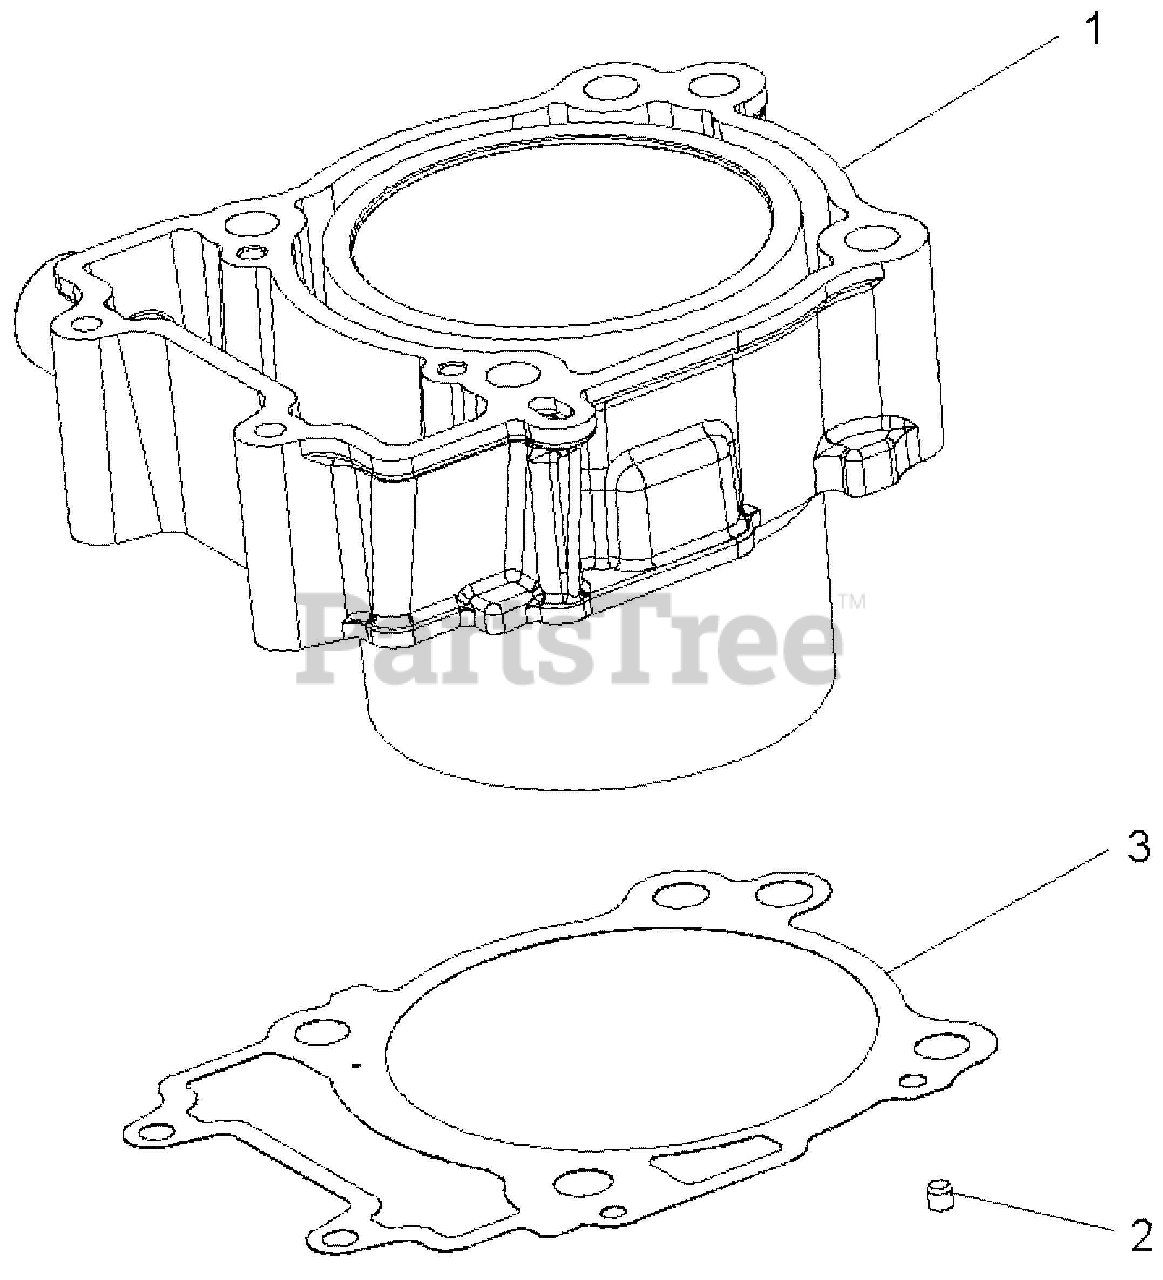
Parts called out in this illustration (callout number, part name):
1	CYLINDER-ASM,99MM
2	PIN-DOWEL,M6X10
3	GASKET-BASE
